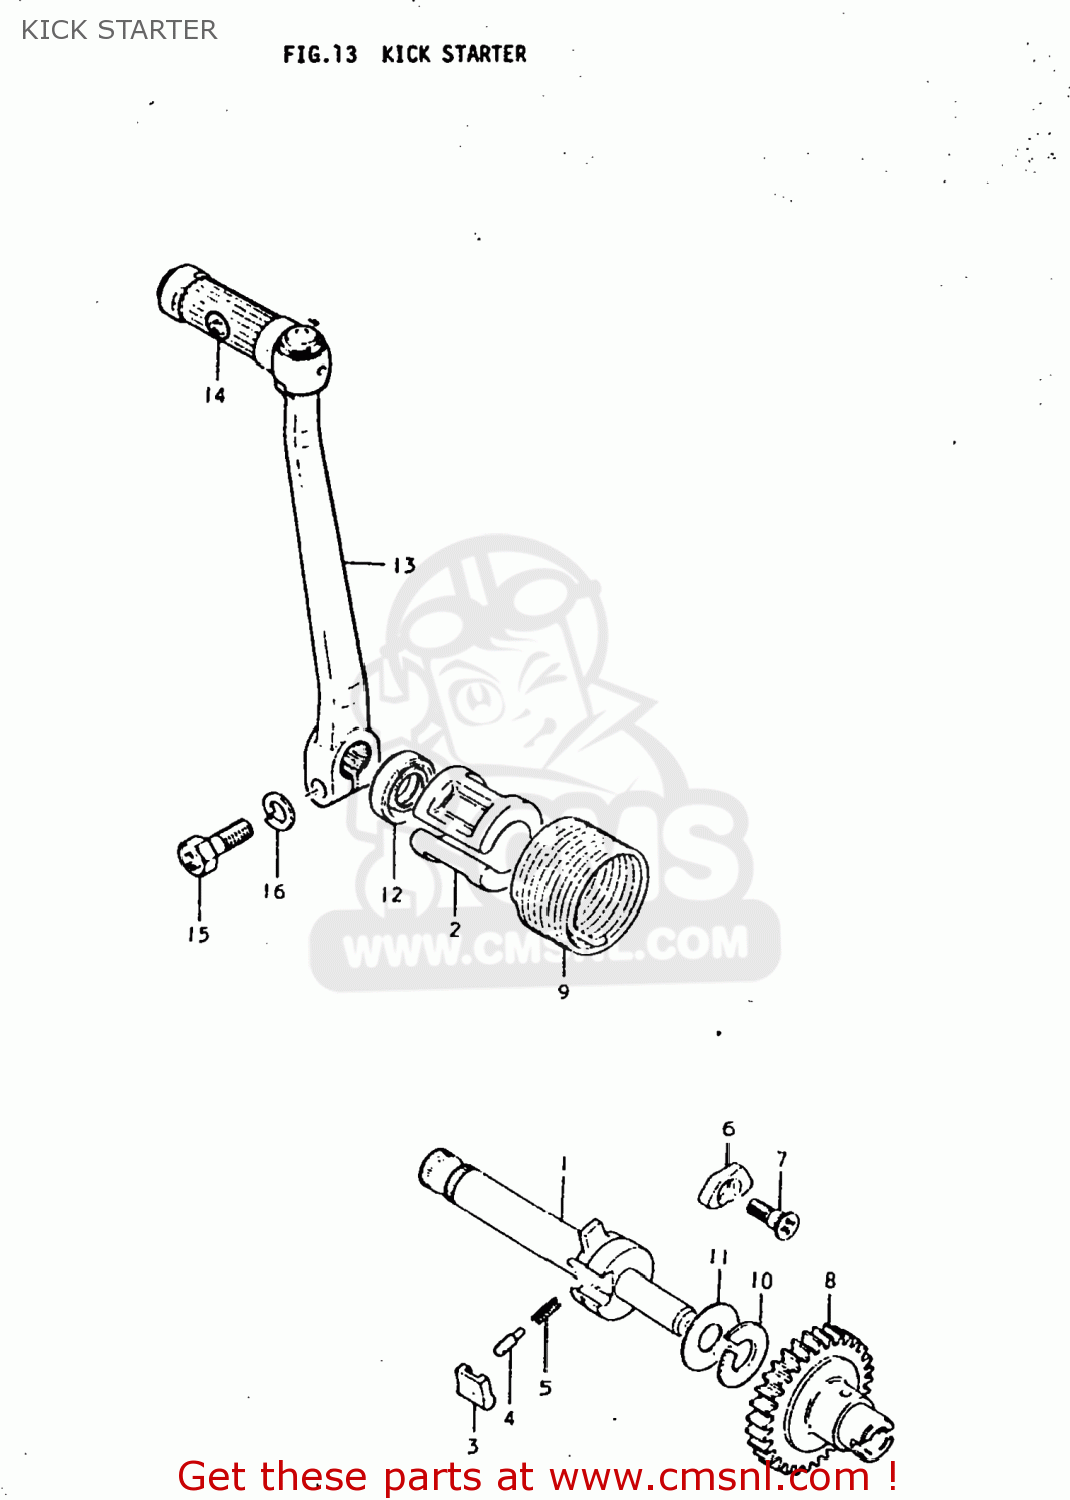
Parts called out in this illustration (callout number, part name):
1	SHAFT,KICK STARTER
2	GUIDE,KICK STARTER SFT SPRING
3	PAWL,KICK STARTER
4	PIN(5X15.5)
5	SPRING
6	LIFTER,KICK STARTER PAWL
7	SCREW(6X19)
8	GEAR,KICK STARTER DRIVE
9	SPRING
10	WASHER,LOCK
11	SHIM(12X30X0.5)
12	SEAL,OIL(16X30X8)
13	LEVER ASSEMBLY,KICK STARTER
14	RUBBER,KICK STARTER PEDAL
15	BOLT
16	LOCK WASHER
